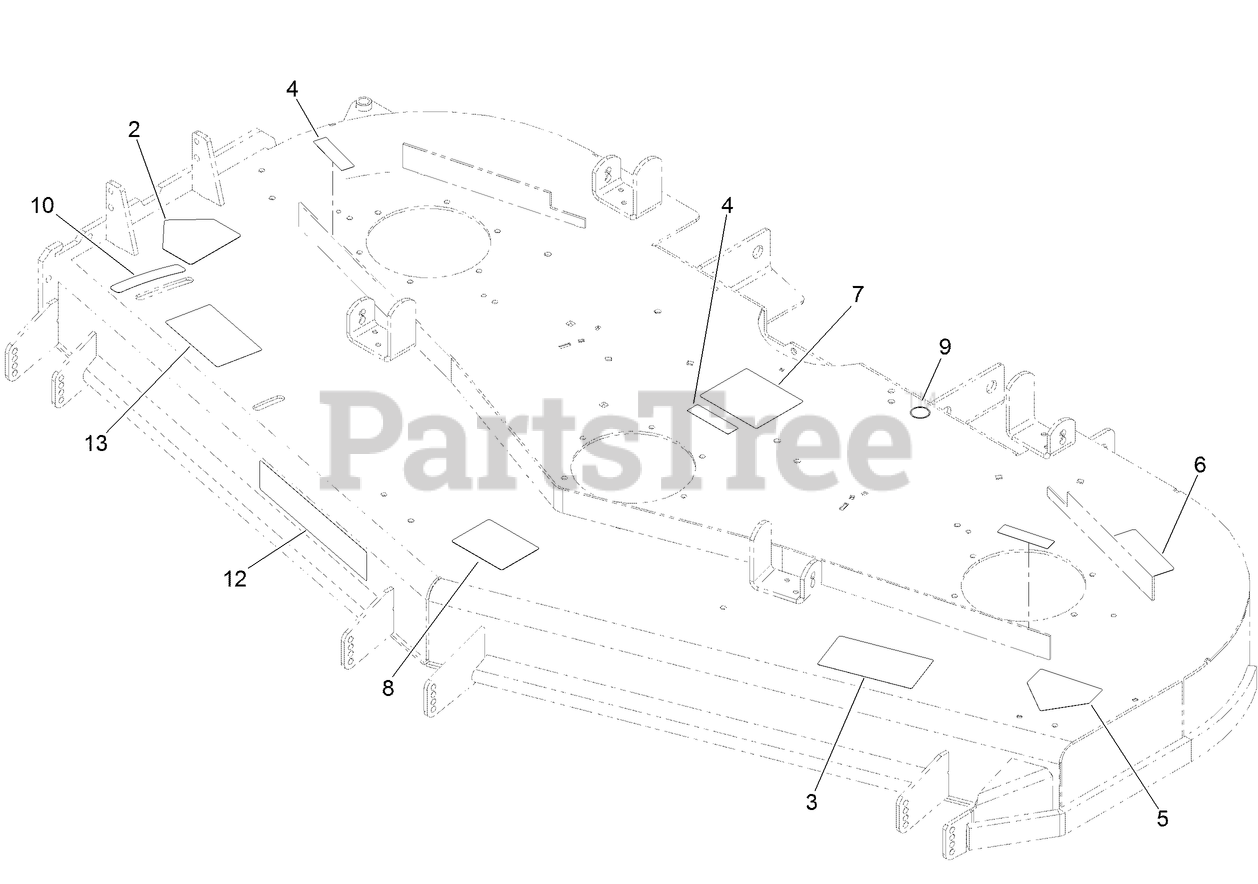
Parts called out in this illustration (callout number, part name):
3	DECAL-DANGER, THROWN OBJECT
4	DECAL-COVER, MISSING
5	DECAL-DANGER
6	DECAL-TORQUE
7	DECAL-ROUTING, BELT
8	DECAL-SCALP, ANTI
9	DECAL-GREASE
10	DECAL-SETTING, BAFFLE
13	DECAL-ADJUSTMENT, BAFFLE
